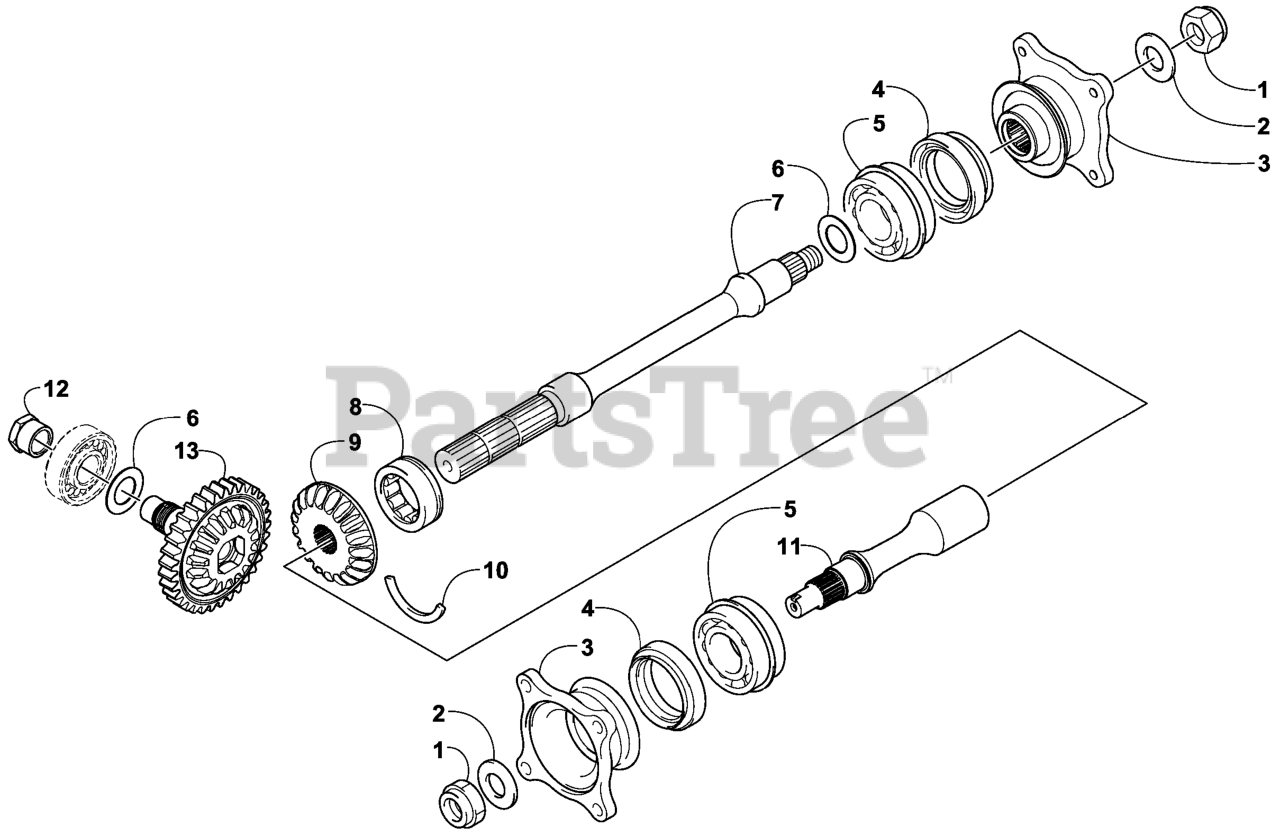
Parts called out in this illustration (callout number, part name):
1	NUT-HH, SHOULDER
2	WASHER-STEEL
3	FLANGE-OUTPUT JOINT, REAR
4	SEAL-OIL, DRIVEN SHAFT
5	BEARING-DRIVEN, SHAFT
7	SHAFT-DRIVE, SECONDARY (1
8	BEARING-DRIVEN, GEAR
9	GEAR-DRIVEN, SECONDARY
10	RING-DRIVEN BEARING
11	SHAFT-SECONDARY DRIVEN, R
13	GEAR-SECONDARY
